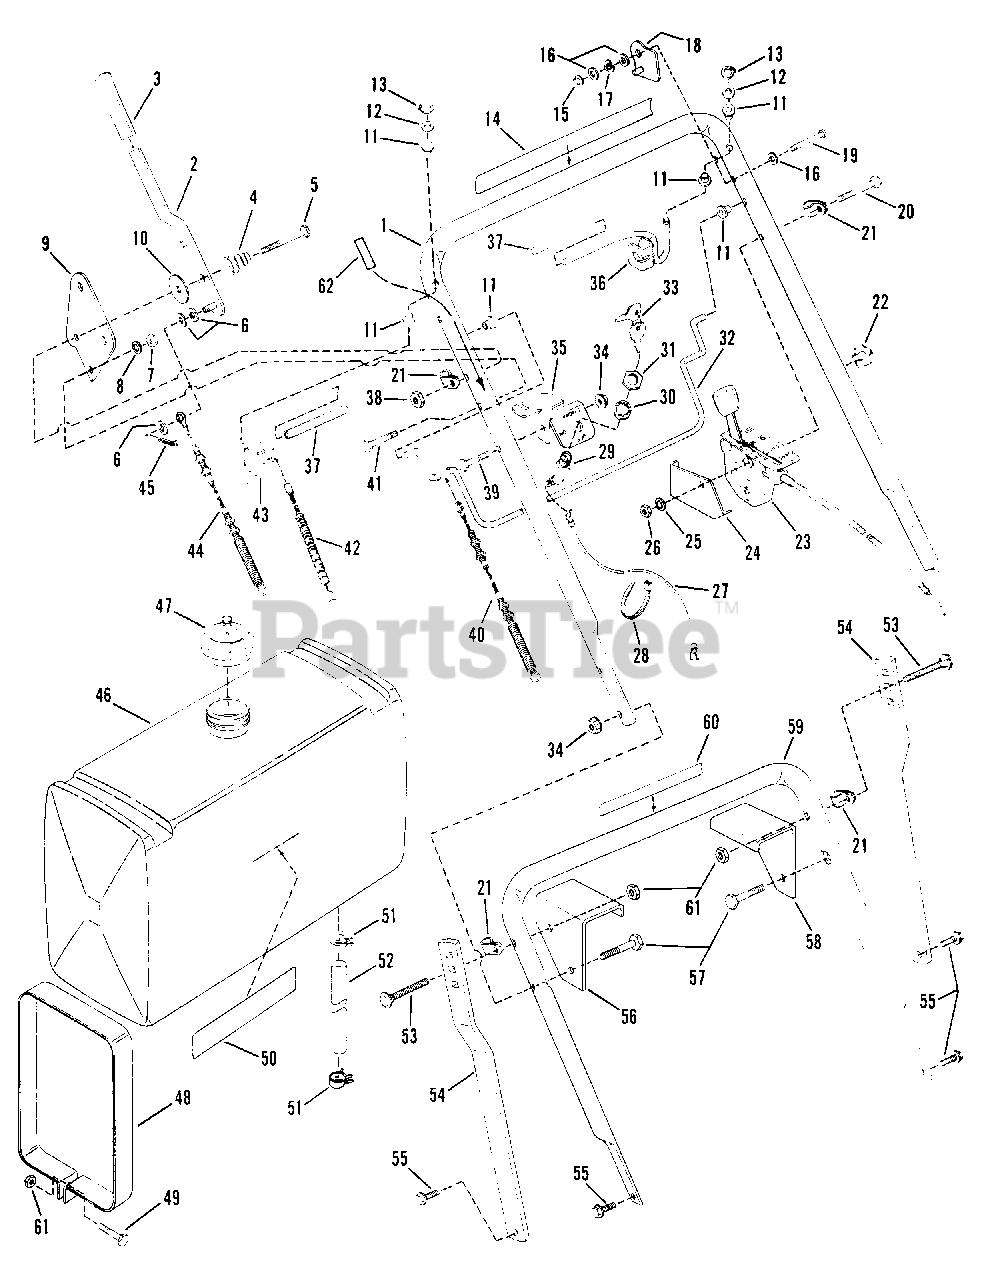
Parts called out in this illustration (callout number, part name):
1	HANDLE, Upper
2	HANDLE, Blade Control
3	GRIP, Blade Control Handle
5	CAPSCREW, 5/16-24 x 2-1/4" Hex Head
6	WASHER, 5/16 Flat
7	NUT, 5/16-24 Hex
8	WASHER, 5/16 Internal Tooth Lock
9	PLATE, Blade Control
10	WASHER
11	BUSHING
12	WASHER, Flat
13	RING, Retaining
14	DECAL, Wheel Drive
15	PUSHNUT
16	WASHER, 1/4 SAE
17	WASHER, 5/16 Wave
18	ASSEMBLY, Brake Lock
19	PIN, Brake Lock
20	CAPSCREW, 1/4-28 x 2" Hex Head
21	GUIDE, Cable
22	CLIP
23	CONTROL, Throttle
24	STOP, Wheel Drive Control
25	WASHER, 1/4 Internal Tooth Lock
26	NUT, 1/4-28 Hex
27	WIRE, Ground
28	CABLE-TIE
29	SWITCH, Ignition
30	WASHER, 5/8 Internal Tooth Lock
31	NUT, 5/8-32 Hex
32	CONTROL, Wheel Drive
33	KEY, Switch (Pair)
34	NUT, 5/16-18 Hex Flange Lock
35	BRACKET, Switch
36	HANDLE, Brake Control, L.H.
37	GRIP, Brake Control Handle
38	NUT, 5/16-24 Hex Center Lock
39	CAPSCREW, 5/16-18 x 1-1/2" Hex Head
40	CABLE, Wheel Drive
41	CAPSCREW, 5/16-24 x 1-1/2" Hex Head
42	CABLE, Brake
43	HANDLE, Brake Control, R.H.
44	CABLE, Blade Control
45	COTTER-PIN, 1/16 x 1/2"
46	TANK, Fuel
47	CAP, Fuel Tank
48	STRAP, Fuel Tank
49	CAPSCREW, 5/16-18x1-1/4"
50	DECAL, Snapper
51	CLAMP, Fuel
52	HOSE, Fuel
53	BOLT, 5/16-18 x 2-1/2" Short Neck Carriage
54	BRACE, Lower Handle
55	SCREW, 5/16-18 x 3/4" Self-Tapping
56	BRACKET, Fuel Tank (R.H.)
57	CAPSCREW, 5/16-18 x 1-3/4" Hex Head
58	BRACKET, Fuel Tank (L.H.)
59	HANDLE, Lower
60	DECAL, Shift
61	NUT, 5/16-18 Top Lock
62	DECAL, Blade Control
